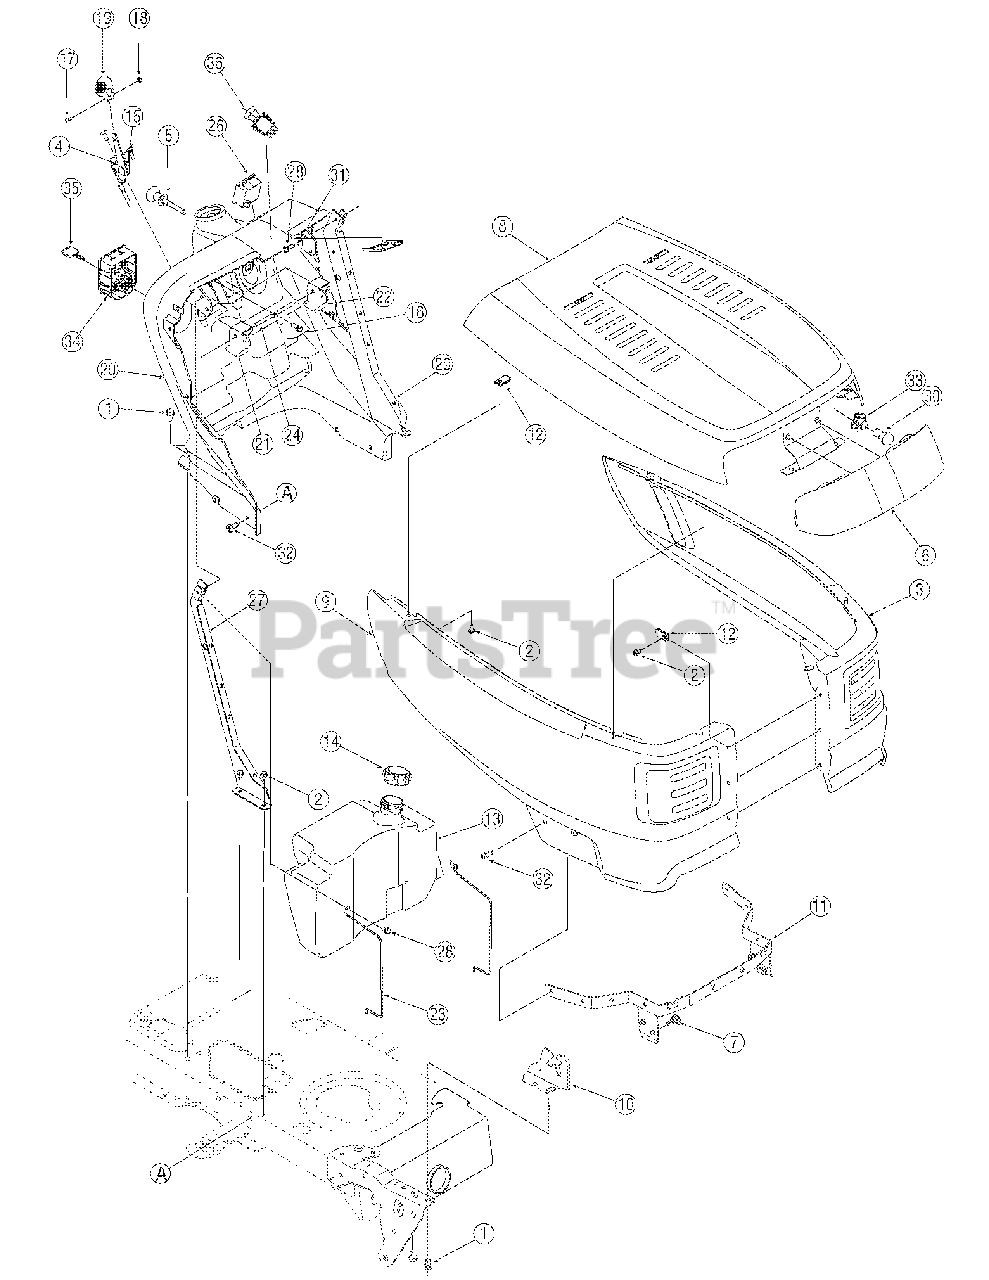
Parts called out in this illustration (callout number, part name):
1	Screw, 5/16-12 x.750
2	Self-tapping Screw, 1/4-20 x.5
5	Choke Control
5	Choke Control, Graphic with wording & symbols
6	Headlight Lens
7	Shoulder Screw,.43 x.29
12	Speed Nut
13	Fuel Tank, Three Gallon
14	Fuel Cap
15	Screw, 1/4-14 x.625
16	Self-tapping Screw, 1/4-15 x.75
17	Truss Phillips Screw, #8-32 x.375
18	Hex Nut, #8-32
19	Throttle Control Knob
20	Dash Panel
21	Cruise Control Button
21	Cruise Control Button, Graphic with wording & symbols
22	Parking Brake Button
22	Parking Brake Button, Graphic with wording & symbols
23	Tank Support Rod
24	Brake/Cruise Pivot Rod
26	Systems Ind. Monitor w/ Hour Meter
30	Lamp
31	Bell Washer,.265 x.75 x.062
32	Screw, 5/16-18 x.75
33	Headlight Socket
34	Ignition Switch
35	Ignition Key w/ plastic cover
35	Ignition Key w/o plastic cover
36	Electric PTO Switch
